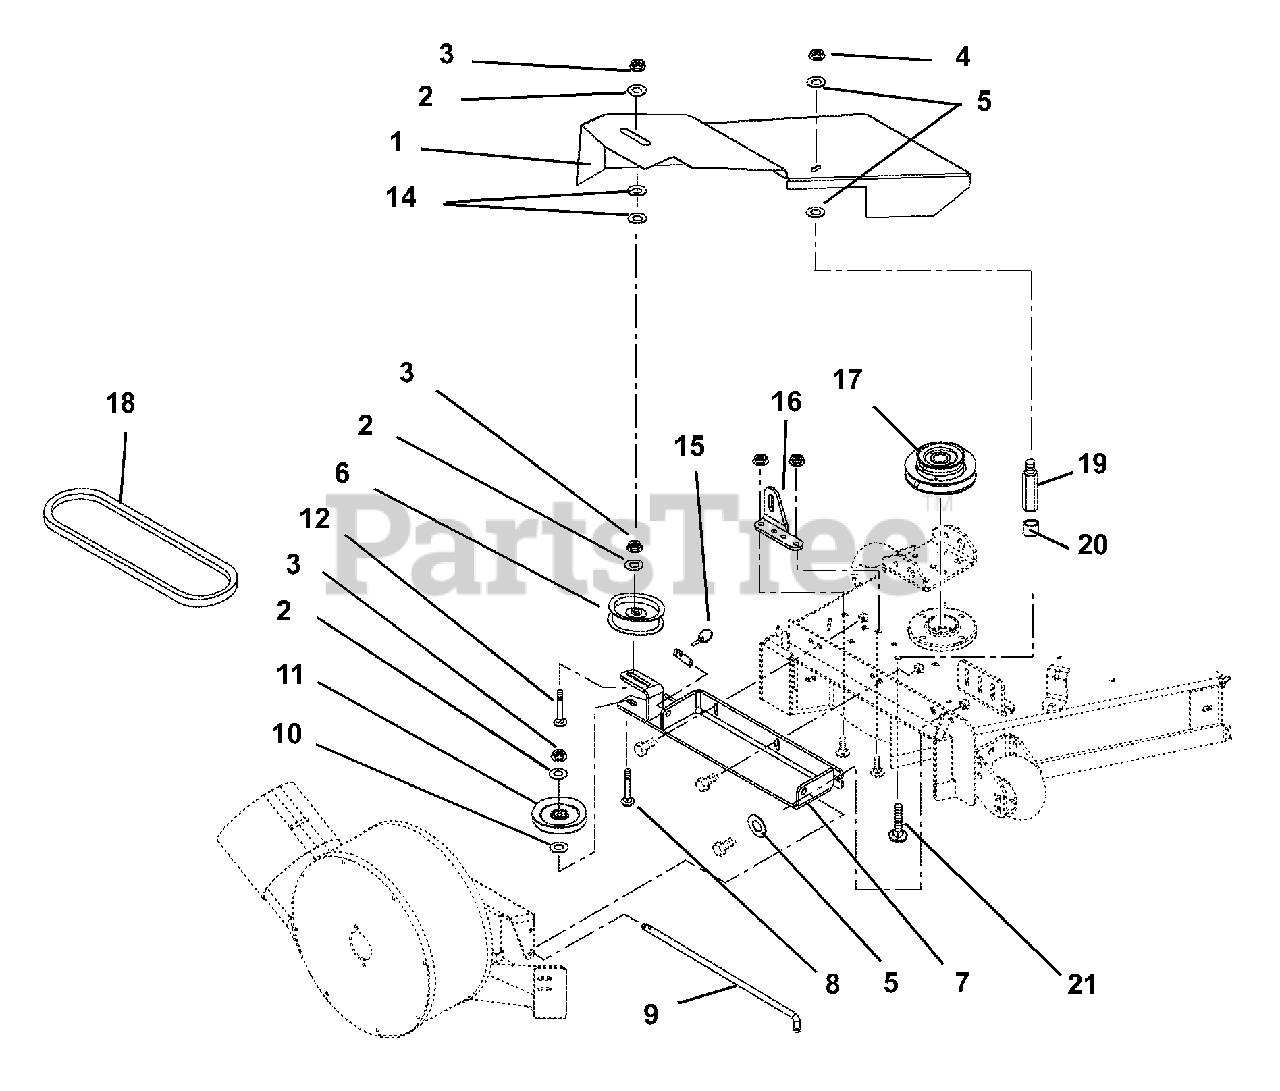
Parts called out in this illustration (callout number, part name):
1	Weldment, Belt Guard
2	Washer-Flat-Steel .438 x 1.00 x .083
3	Nut-Locking-Top-Flange .38-16
4	Nut-Locking-Top-Flange .31-18
5	Washer-Flat-Steel .38 x .875 x .083
6	Idler Flanged 3.50
7	Weldment, Pivot Mount 44,48,52
8	Bolt-Round Head Square Neck .38-16 x 1.75 Grade 5
9	Rod, Pivot
10	Washer-Flat-Steel .406 x 1.00 x .188
11	Idler-V 4.00 x .38
12	Bolt-Round Head Square Neck .38-16 x 2.50 Grade 5
13	Nut-Locking-Center .31-18
14	Washer-Flat-Steel .406 x 1.375 x .135
15	Pin-Klik 1.00 x .188 x 1.25
16	Bracket, 52-Inch Deck Mounting
17	Pulley, Double V 3.50/5.25 Diameter
18	V-Belt 52-Inch Mower Deck
19	Standoff, 2.75 x 5/16-18
20	Spacer, .380 x .503 x .281
21	Bolt-Round Head Square Neck .31-18 x 1.00 Grade 5
